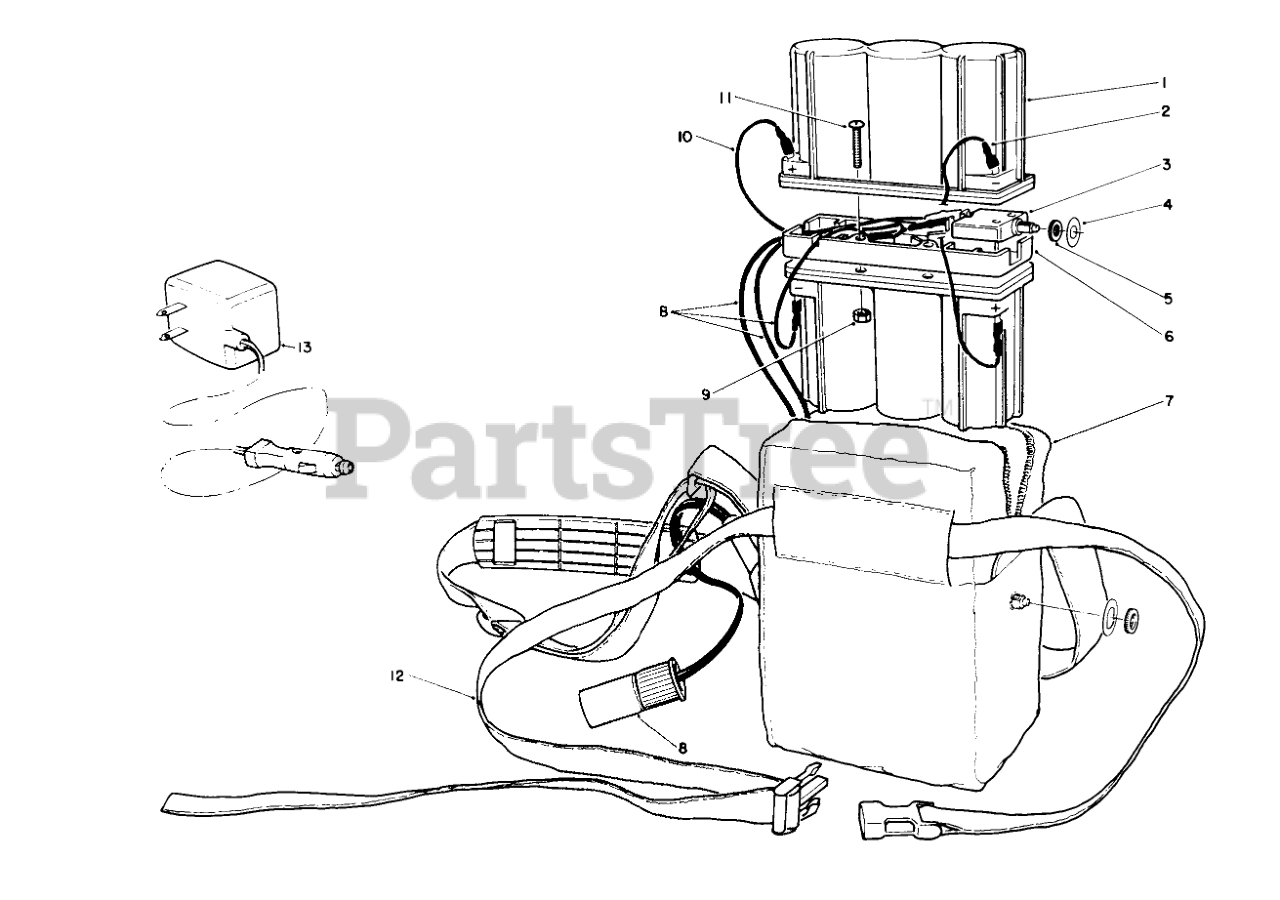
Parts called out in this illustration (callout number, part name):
1	BATTERY, 6 VOLT
2	WIRE ASSEMBLY-BATTERY
3	CKT BREAKER 15 AMP 125V
4	CIRCUIT BREAKER PLATE
5	KNURLED NUT
6	BATTERY SPACER
7	Pack-Soft
8	CORD-BATTERY PACK
9	NUT-HEX
10	WIRE ASSY-CIRCUIT BREAK
11	SCREW-PPH
12	BELT-WAIST
13	Charger 12 Volt
